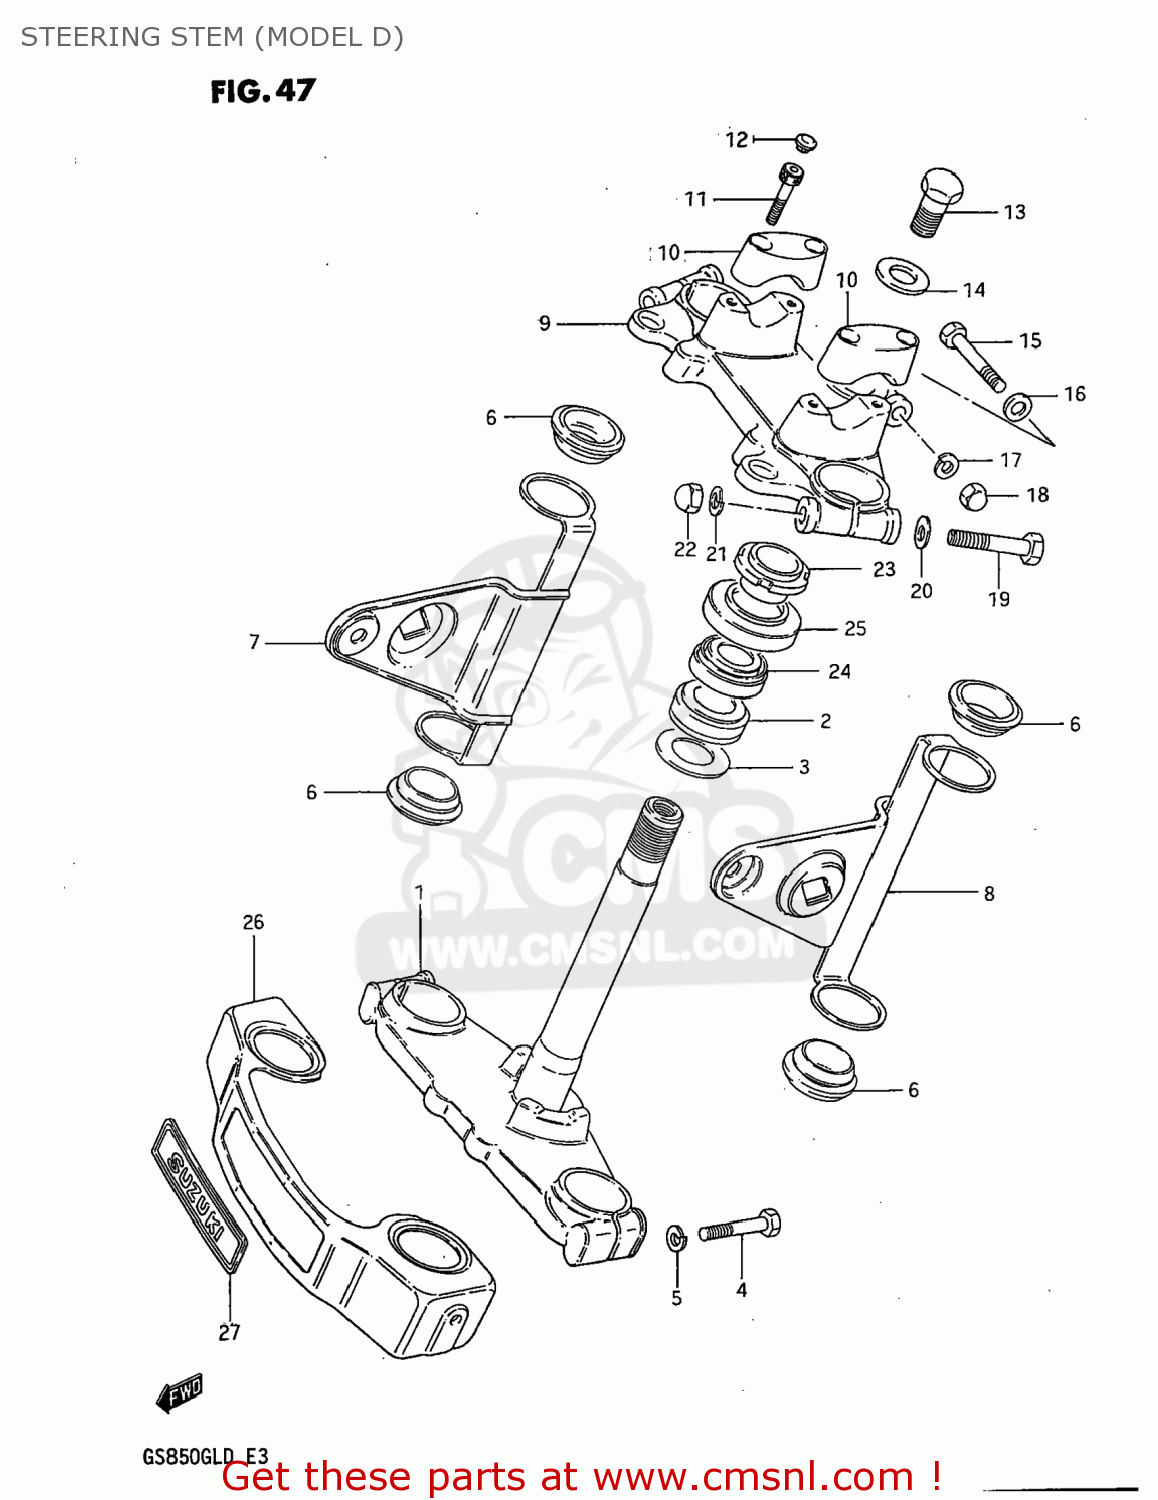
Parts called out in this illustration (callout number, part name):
1	STEM,STEERING
2	BEARING
3	WASHER,THRUST
4	BOLT
5	LOCK WASHER
6	CUSHION,HEADLAMP BRACKET
7	BRACKET,HEADLAMP,RIGHT
8	BRACKET,HEADLAMP,LEFT
9	HEAD,STEERING STEM
10	HOLDER,HANDLEBAR
11	BOLT
12	CAP(OD:14.5)
13	NUT,STEM HEAD
14	WASHER,STEERING STEM
15	BOLT 8X50
16	WASHER
17	WASHER,LOCK,8.
18	NUT
19	BOLT 10X55
20	WASHER
21	LOCK WASHER
22	NUT, LOWER LH
23	NUT,STEERING STEM
24	TAPER,ROLLER BEARING
25	DUST SEAL,STEERING UPR
26	COVER,FRONT FORK
27	EMBLEM,FRONT FORK COVER
